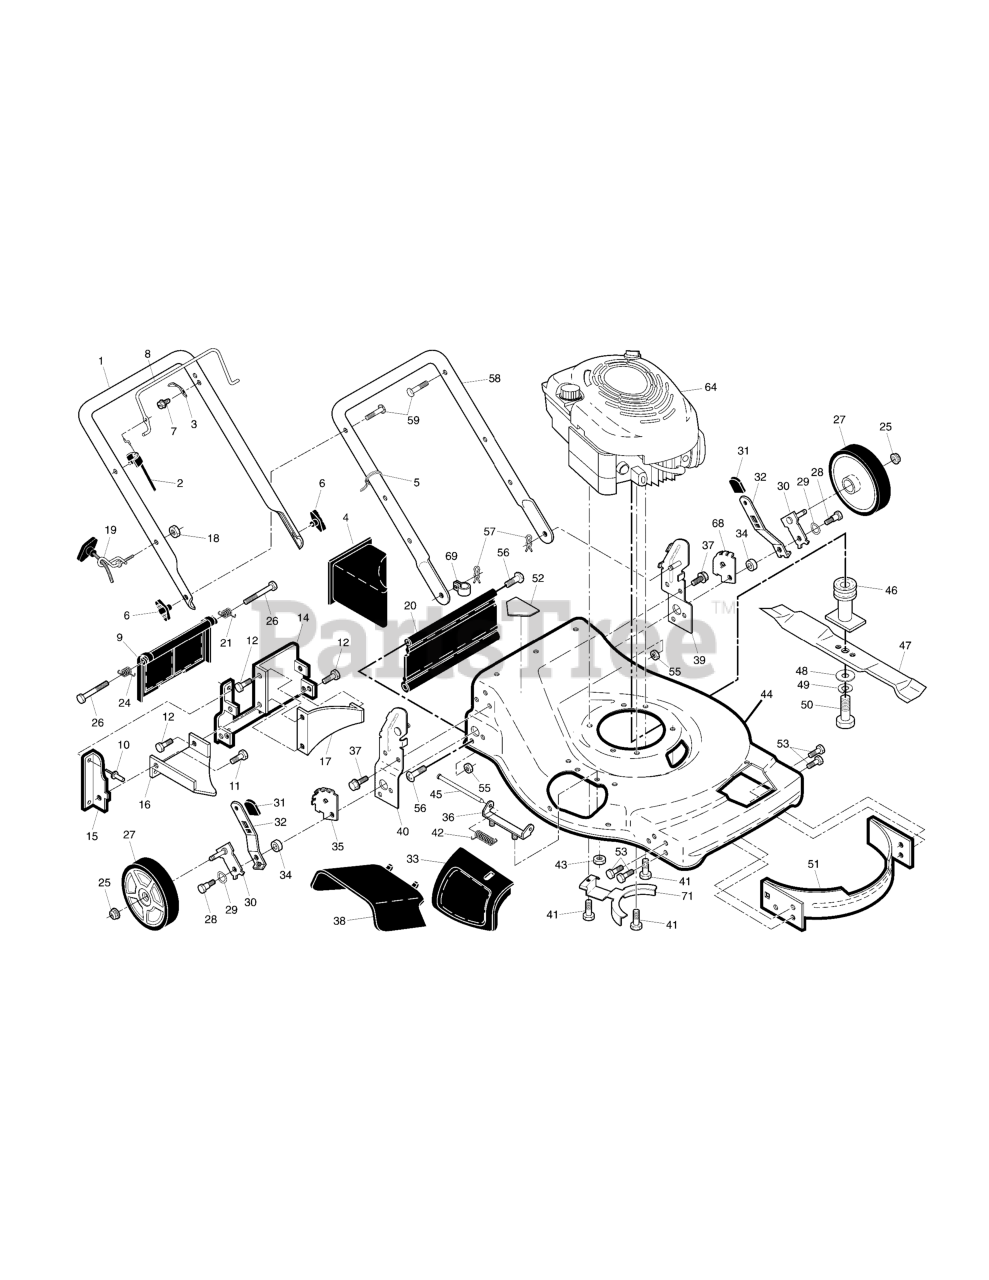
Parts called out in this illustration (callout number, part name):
1	Upper Handle
2	Engine Zone Control Cable
3	Bracket, Upstop
4	Mulcher Plug
5	Wire Tie
6	Handle Knob
8	Control Bar
9	Rear Door Assembly
10	Pop Rivet
11	Screw, Self-Tapping, #10-24 X 5/8
12	Screw, Sems, Hex Head, 1/4-20 X 1/2
14	Back Plate
15	Side Baffle
16	Discharge Baffle
17	Rear Baffle
18	Keps Locknut 1/4-20
19	Rope Guide
20	Rear Skirt
21	Spring, Rear Door, LH
24	Spring, Rear Door, RH
25	Nut, Hex, Flanged
26	Bolt, Rear Door
27	Wheel & Tire Assy., Rear
28	Bolt, Shoulder 3/8-16 x 1
29	Washer, Curved, Cylindrical
30	Axle Arm Assembly
31	Selector Knob
32	Selector Spring
33	Mulcher Door
34	Spacer
35	Wheel Adjusting Bracket, RH
36	Hinge Bracket
37	Screw
38	Discharge Defl ector
39	Handle Bracket Assy., LH
40	Handle Bracket Assy., RH
41	Screw, Hex Head, Thread Roll, 3/8-16 x 1-1/8
42	Hinge Spring
43	Nut, Hex, Nylock
44	Kit, Housing (Includes Ref. Nos. 14, 15 & 51)
45	Hinge Rod
46	Blade Adapter / Pulley
47	Blade, 22"
48	Washer, Hardened
49	Washer, Helical
50	Screw, Machine, Hex Head, 3/8-24 x 1-3/8, G8
51	Kit, Front Baffle (Includes Ref. 53)
52	Danger Decal
53	Screw, Serrated, Type TT, 1/4-20
55	Nut, Hex 3/8-16
56	Hinge Screw 1/4-20 x 1-1/4
57	Hairpin Cotter
58	Lower Handle
59	Handle Bolt
64	* Engine, Briggs & Stratton
68	Wheel Adjusting Bracket, LH
69	Clip, Cable
71	Belt Keeper
